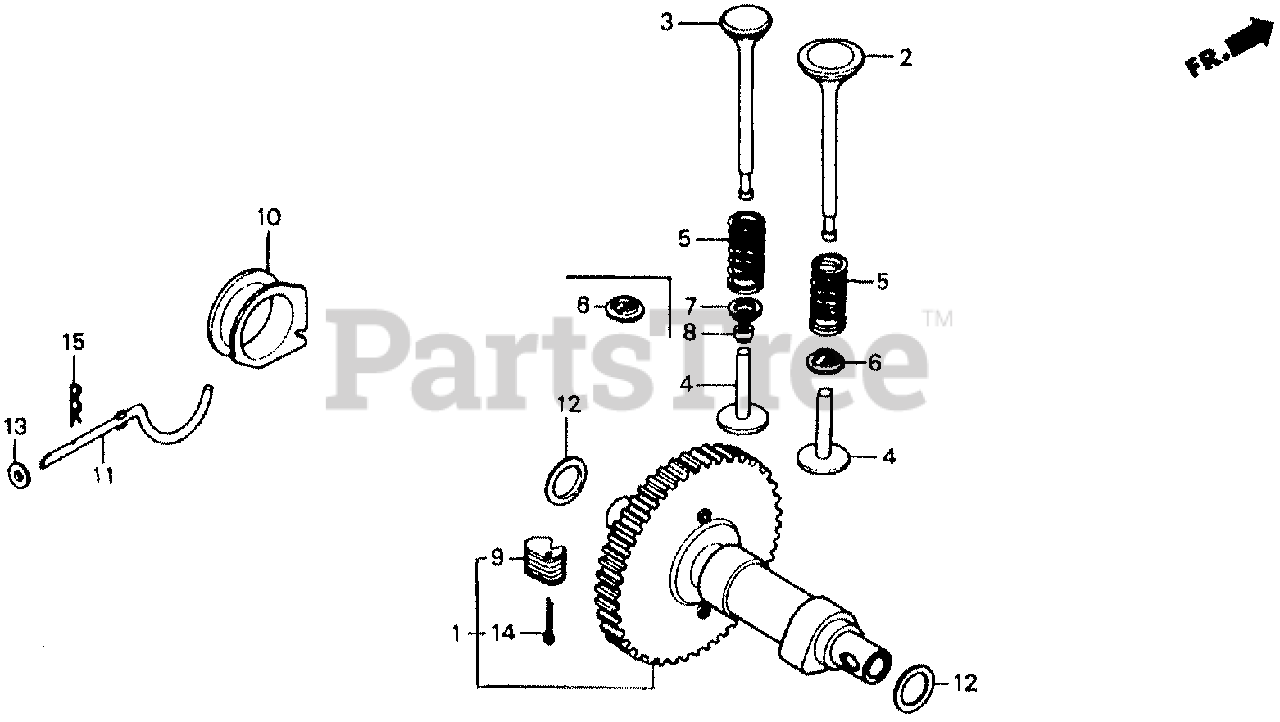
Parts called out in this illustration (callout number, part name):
1	CAMSHAFT ASSY.
2	VALVE, IN.
3	VALVE, EX.
4	LIFTER, VALVE (45.89MM)
4	LIFTER, VALVE (46.04MM)
4	LIFTER, VALVE (46.19MM)
4	LIFTER, VALVE (46.34MM)
5	SPRING, VALVE
6	RETAINER, VALVE SPRING
7	RETAINER, VALVE SPRING
8	ROTATOR, EX. VALVE
9	WEIGHT, GOVERNOR
10	SLIDER, GOVERNOR
11	SHAFT, GOVERNOR
12	WASHER, THRUST (18MM)
13	WASHER, PLAIN (6MM)
14	PIN, COTTER (3.0X45)
15	PIN, LOCK (10MM)
